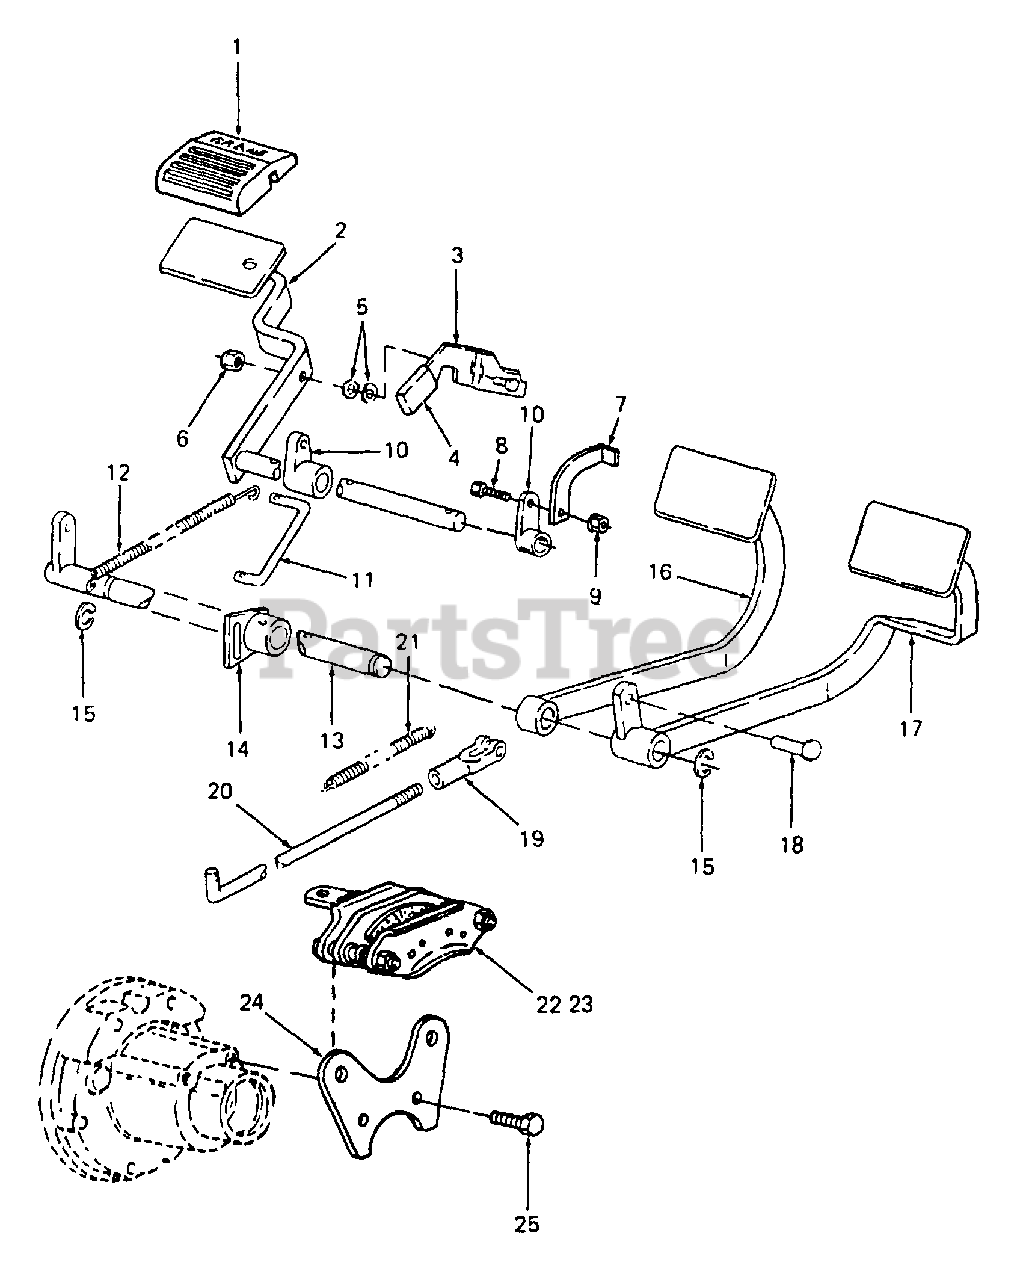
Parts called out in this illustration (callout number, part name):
1	Pad, Brake Pedal
5	Washer, Wave, 1/4 Dia
6	Nut, Hex Insert Lock, 1/4-20
8	Screw, Hex Cap, 3/8-16 x .75 Lg GR5
9	Nut, Hex Flanged Lock, 3/8-16 GR5
11	Rod, Center Brake
12	Spring, Extension, .50 OD x 7.32 Lg
13	Shaft Assy, Brake
14	Arm Assy, Parking Brake Plate
15	Ring, Retaining
18	Pin, Clevis, 3/8 Dia x 1.56 Lg
19	Clevis, Adjustment
20	Rod, Brake
21	Spring, Extension, .66 OD x 3.3 Lg
22	Brake Kit, RH Caliper
24	Bracket, Brake Mounting
25	Screw, Hex Cap, 5/16-18 x 1.0 Lg GR5
